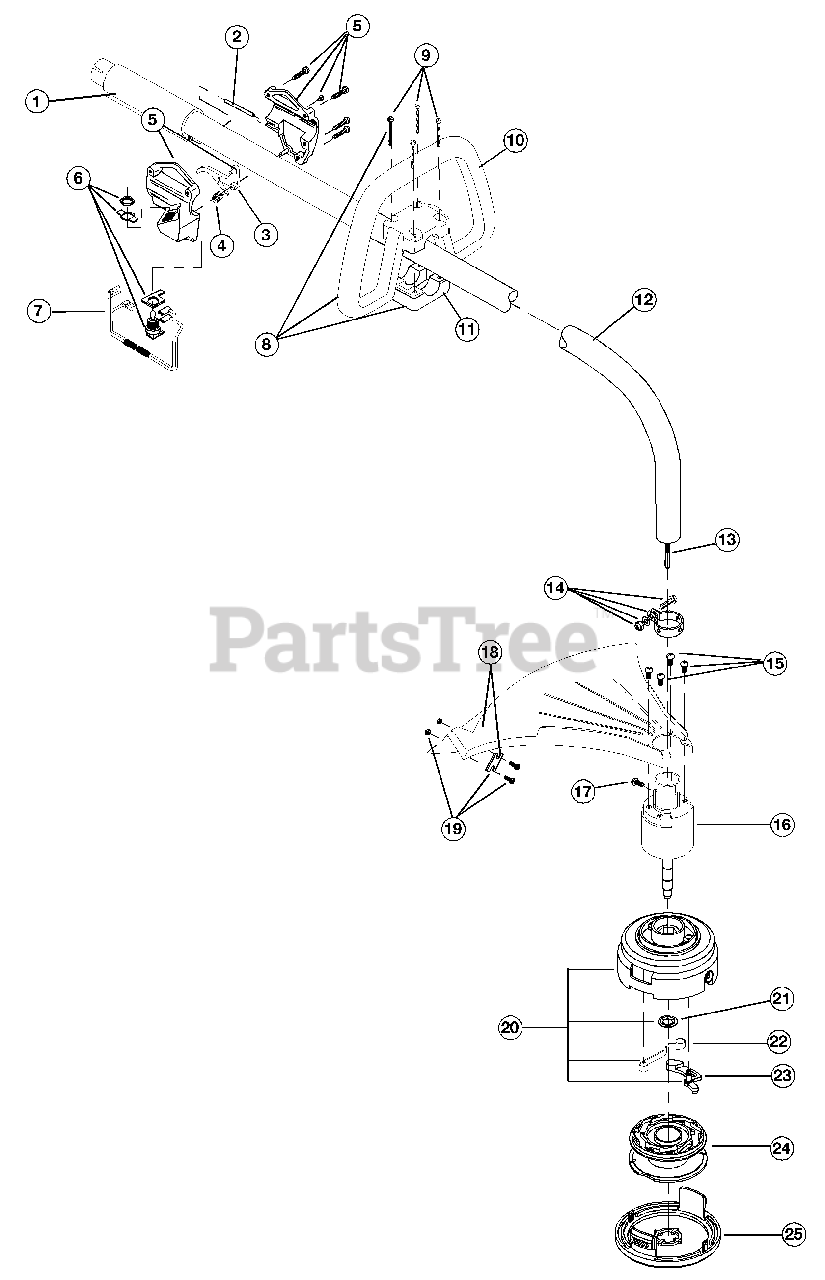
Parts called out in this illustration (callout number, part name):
2	Throttle Cable Assembly
3	Throttle Trigger
4	Throttle Trigger Spring
5	Throttle Trigger Assembly
6	Switch Assembly
7	Wire Lead Assembly
8	Loop Handle Assembly
10	Loop Handle
11	Bottom Clamp
12	Drive Shaft Housing Assembly
13	Flexible Drive Shaft
14	Lower Clamp Assembly
15	Shield Mounting Screw
16	Bushing Housing Assembly
17	Anti-Rotation Screw
18	Shield and Blade Assembly
19	Blade Assembly
20	Outer Spool w/ Retainer
22	Pawl Spring
23	Ratchet Pawl
24	Inner Reel
25	Spool Cover
